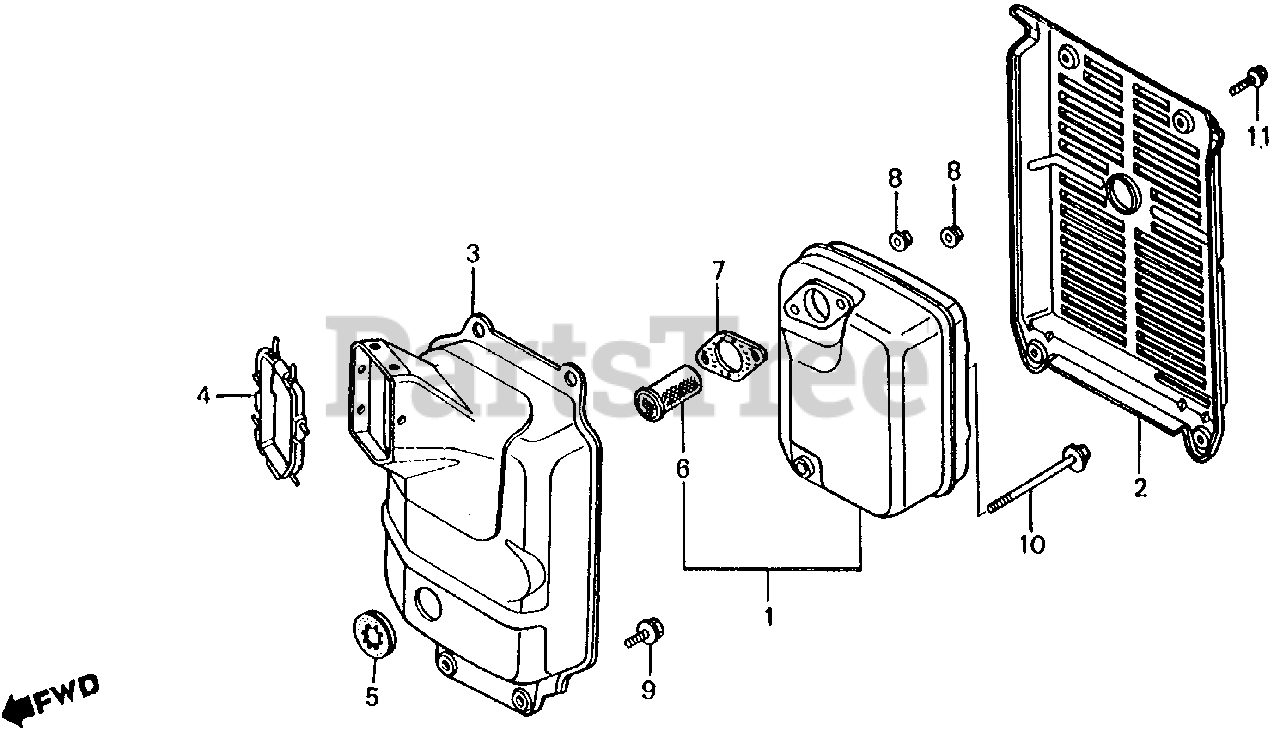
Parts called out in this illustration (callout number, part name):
1	ARRESTER SET, MUFFLER (NOT AVAILABLE)
2	PROTECTOR, MUFFLER (OUTER) *NH105* (MAT BLACK)
3	PROTECTOR, MUFFLER (INNER)
4	RUBBER, PROTECTOR (INNER)
5	SEAL B, MUFFLER PROTECTOR
6	ARRESTER, SPARK
7	GASKET, MUFFLER (NOT AVAILABLE)
8	NUT, FLANGE (6MM)
9	BOLT, FLANGE (6X10)
10	BOLT, FLANGE (6X70)
11	BOLT, FLANGE (6X10)
